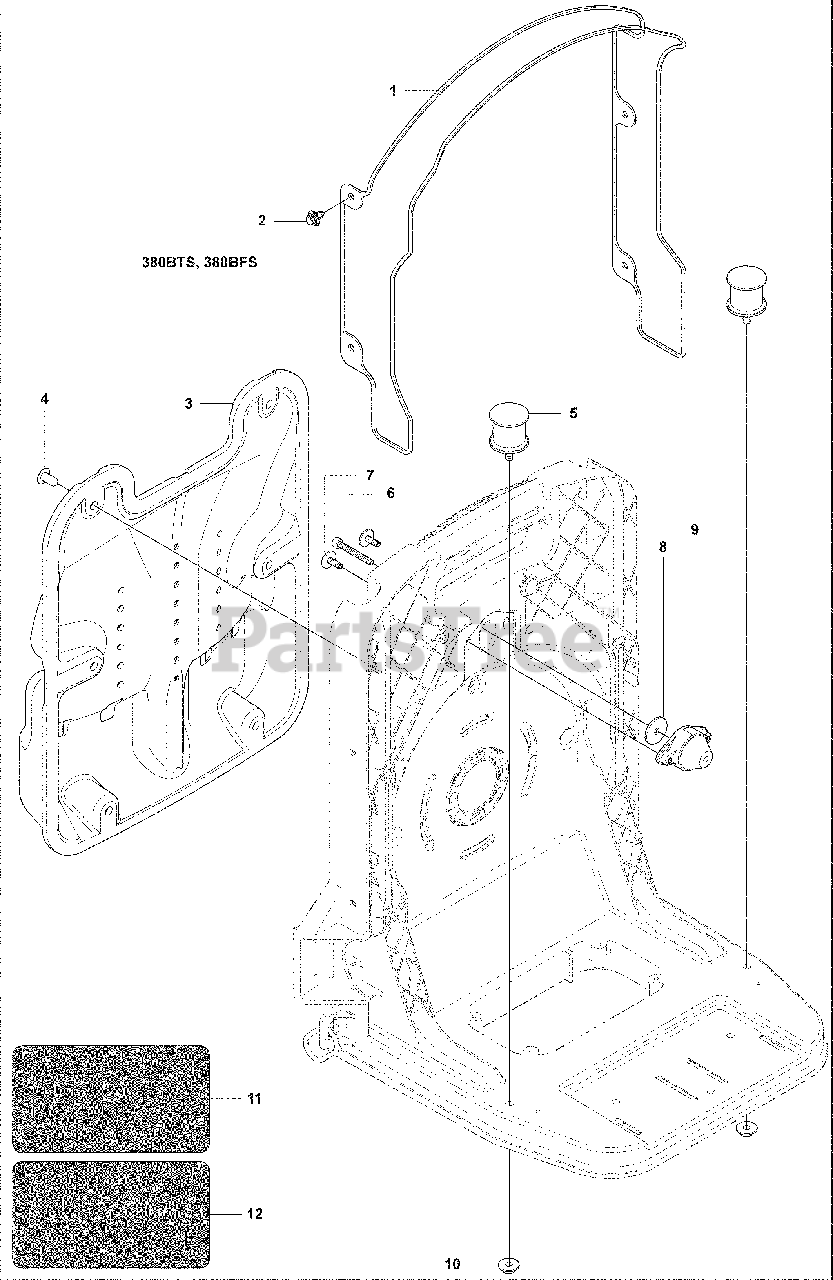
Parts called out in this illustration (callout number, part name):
2	Clip
4	Clip
5	Damper
6	Clip
7	Bolt
8	Washer
9	Upper Damper
10	Nut
